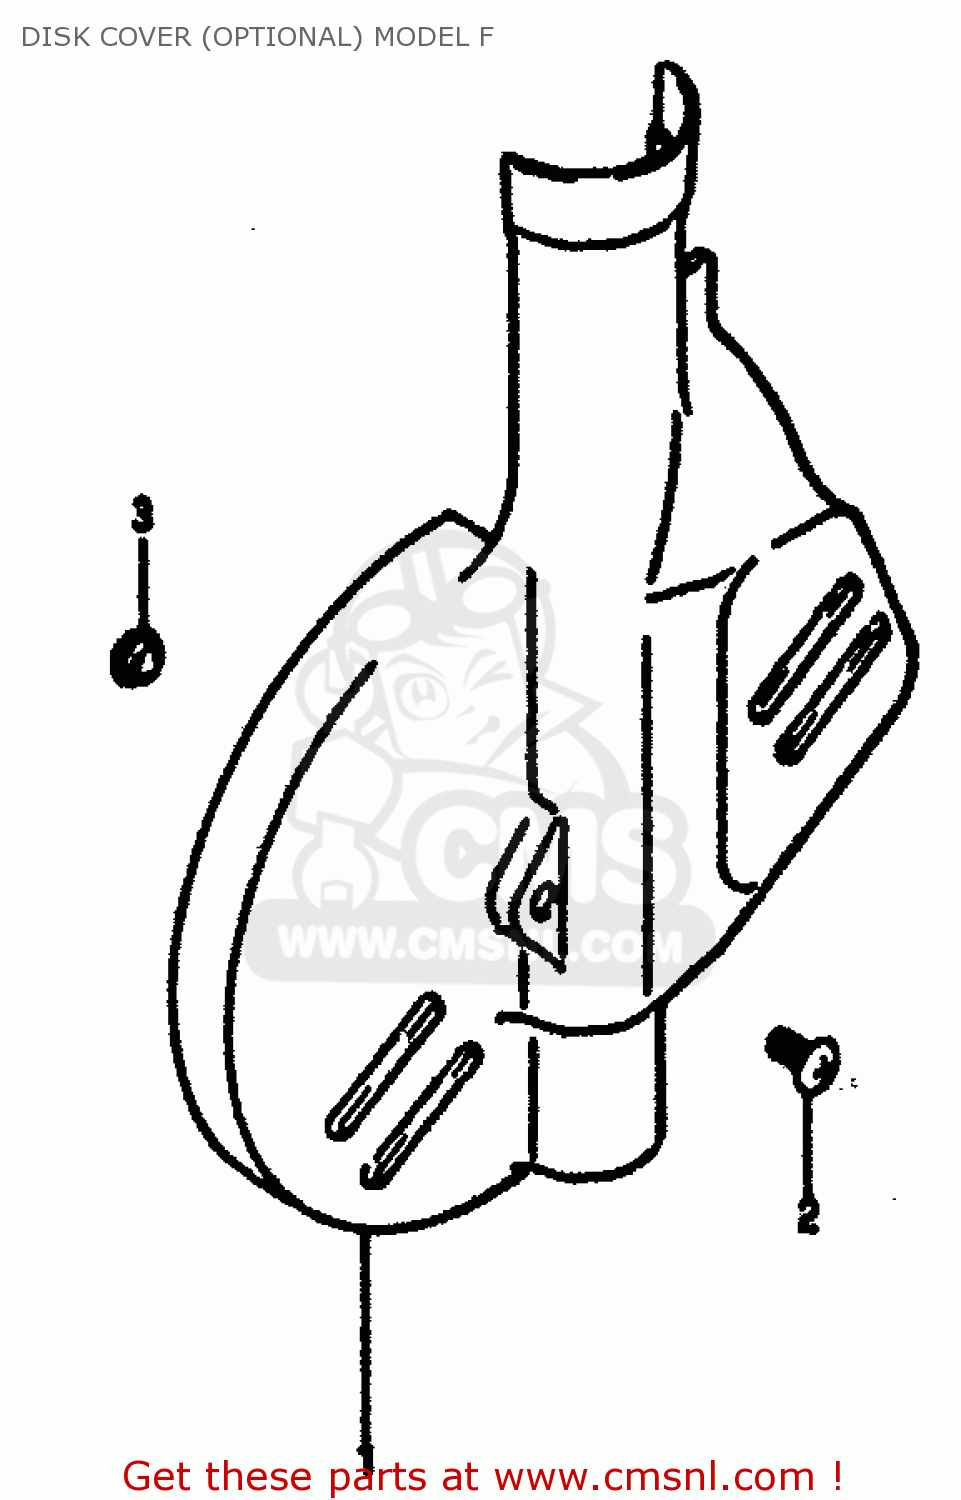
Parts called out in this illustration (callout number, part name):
1	COVER,FRONT BRAKE DISC
2	SCREW(8X12)
3	WASHER
